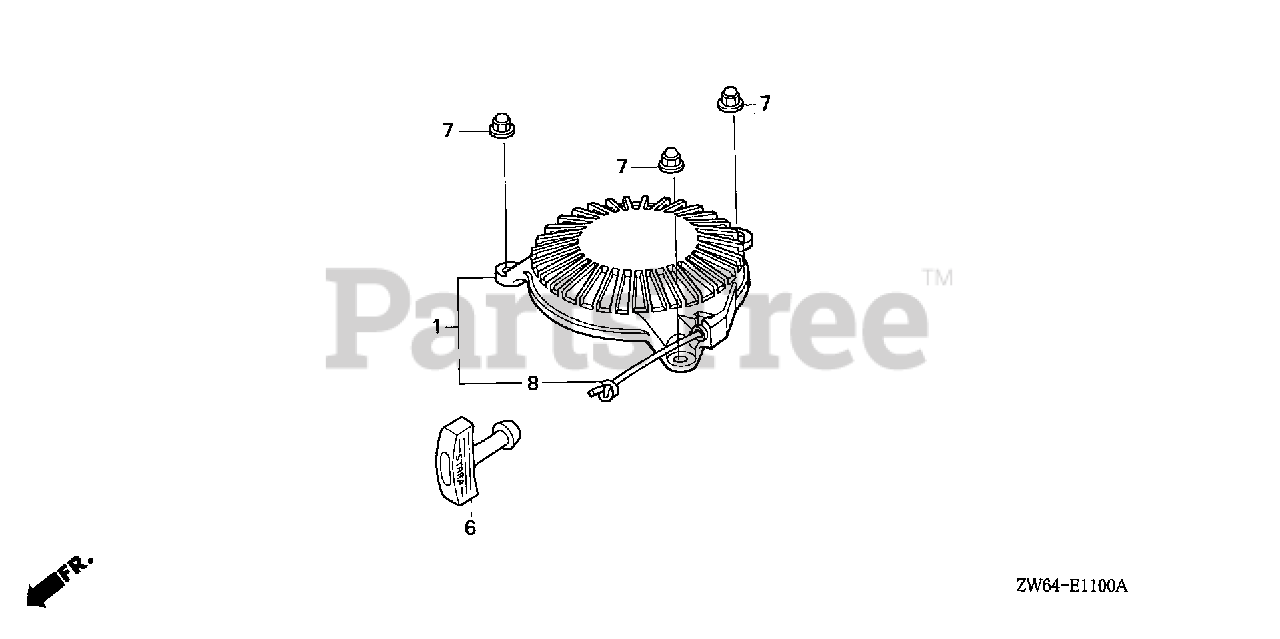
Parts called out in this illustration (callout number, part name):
1	STARTER ASSY., RECOIL
6	KNOB, STARTER
7	NUT, FLANGE CAP (5MM)
8	ROPE, RECOIL STARTER
